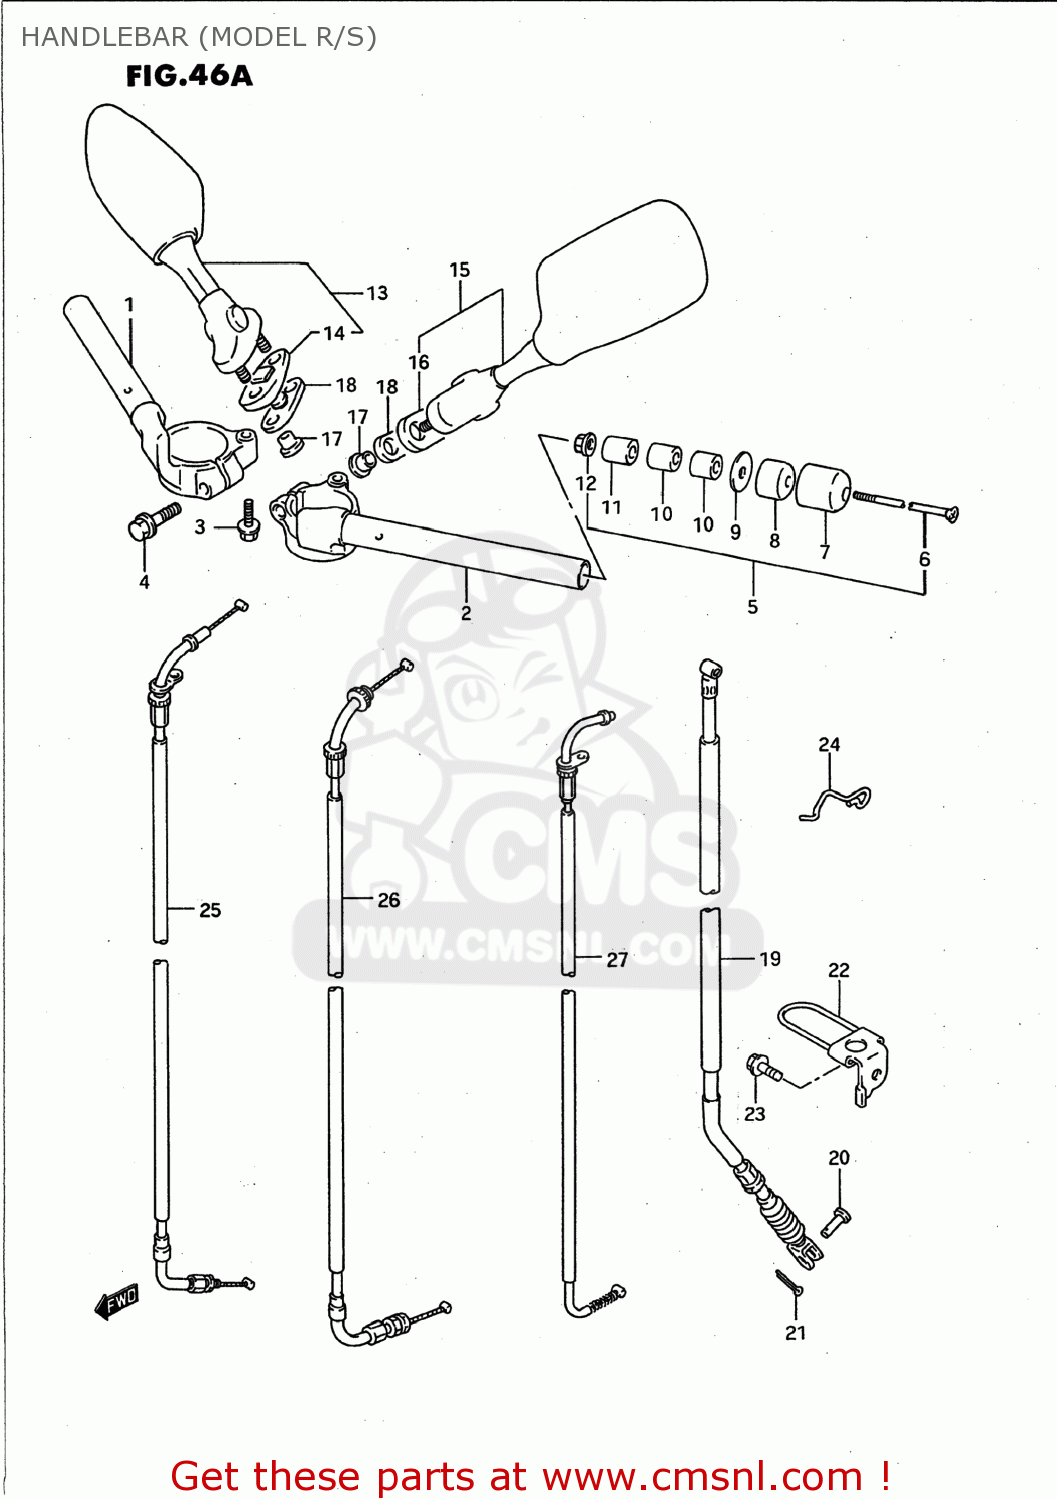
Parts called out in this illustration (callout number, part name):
1	HANDLEBAR,RIGHT
2	HANDLEBAR,LEFT
3	BOLT
4	BOLT(8X30)
5	BALANCER SET,HANDLEBAR
6	SCREW(6X110)
7	CAP,BALANCER
8	BALANCER,HANDLE
9	SPACER,BALANCER
10	BALANCER,HANDLEBAR INNER
11	EXPANDER,HANDLE BALANCER
12	NUT
13	MIRROR ASSEMBLY,REAR VIEW
14	GASKET,RR VIEW MIRROR,R (NAS)
15	MIRROR ASSEMBLY,REAR VIEW
16	GASKET,RR VIEW MIRROR,L (NAS)
17	NUT,RR VIEW MIRROR
18	CUSHION,RR VIEW MIRRORR
19	CABLE ASSY,CLUTCH
20	PIN(L:15)
21	PIN
22	GUIDE,CABLE
23	BOLT
24	GUIDE,CLUTCH CABLE
25	CABLE ASSY,THROTTLE NO.1
26	CABLE ASSY,THROTTLE NO.2
27	CABLE,STARTER
